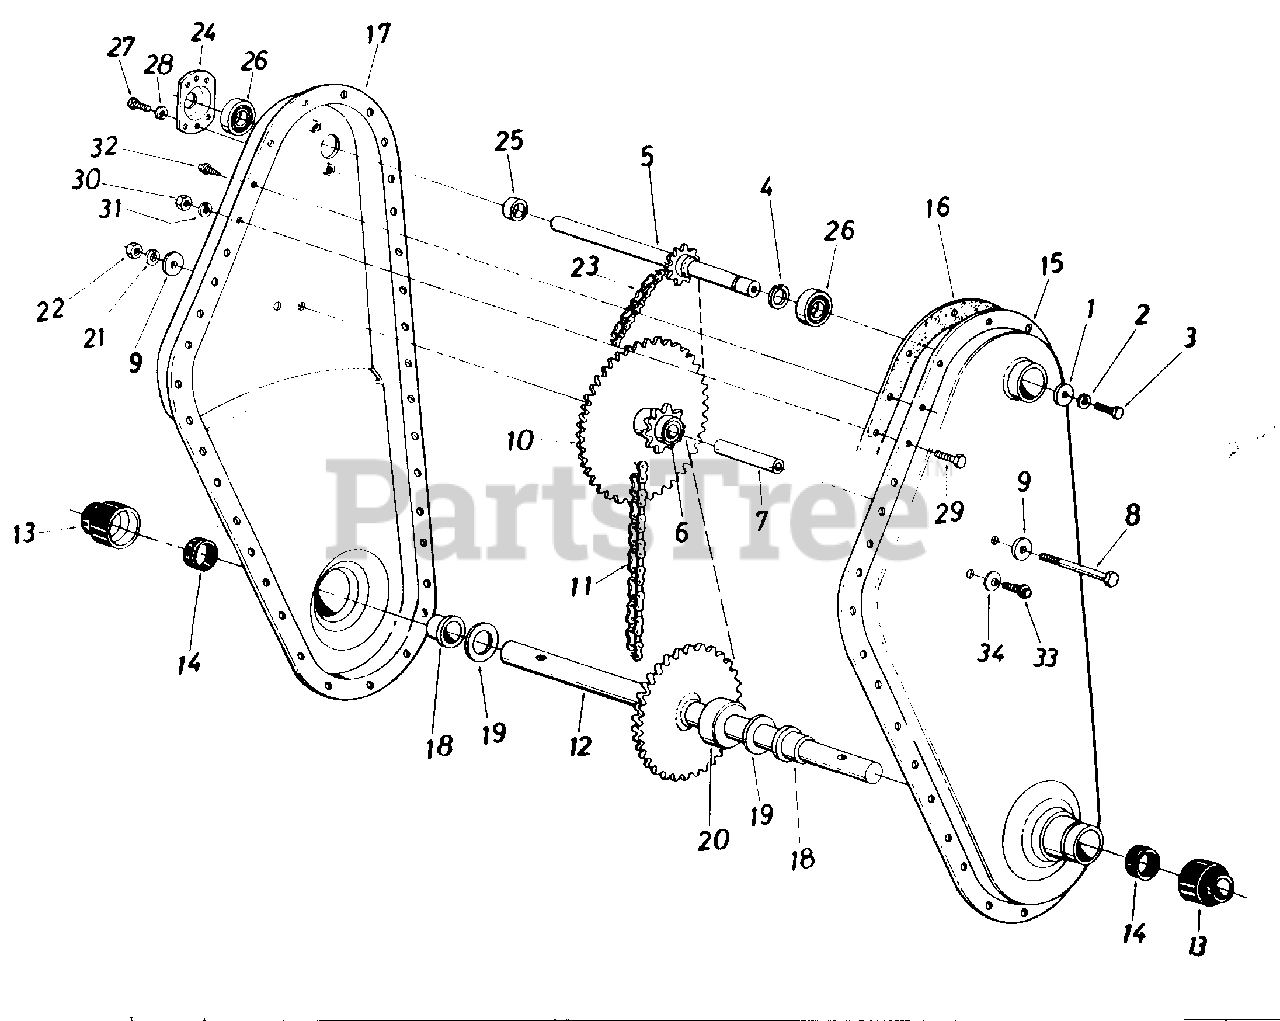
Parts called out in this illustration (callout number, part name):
1	Fl-Wash. 1/4" I.D. x .93" O.D. x . 1 20
2	L-Wash. 1/4" I.D.
3	Hex Bolt 1/4-28 x .62" Lg. w/Patch
4	External Snap Ring-5/8" Dia.
5	Input Shaft Ass'y.
6	Bearing 5/8" I.D. x 3/4" O.D. x 1.860" Lg.
7	Sprocket Hub Tubing 3/8" I.D. x 5/8" O.D. x 1.90
8	Hex Bolt 3/8-24 x 2.75" Lg.
9	Fl-Wash. 3/8" l.D. x 1.25" O.D. x .10
10	Sprocket Ass'y.
11	#50 Chain 5/8" Pitch x 46 Links Endless
12	Tine Shaft Ass'y.
13	Dust Cup
14	Seal Ring Single Lip, Springless
19	Fl-Thrust Wash. 1.0" I.D. x .03 Thk.
20	Step Spacer
21	L-Wash. 3/8" I.D.
22	Hex Nut 3/8-24 Thd.
23	#35 Chain 3/8" Pitch x 52 Links Endless
24	Bearing Housing 1.38" I.D.
25	Spacer
26	Ball Bearing .625" I.D. x 1.38" O.D. x .437
27	Hex Wash. SF-Tap Scr. 1/4-20 x .50" Lg.
28	L-Wash. 1/4" I.D.
29	Hex Bolt 5/16-18 x .75" Lg.
30	Hex Nut 5/16-18 Thd.
31	L-Wash. 5/16" I.D.
32	Hex Wash. SF-Tap Scr. 1/4-20 x .50" Lg.
33	Hex Wash. Hd. Tap Scr. 1/4-20 x .38" Lg.
34	Bell-Wash. .265" I.D. x .75" O.D.
